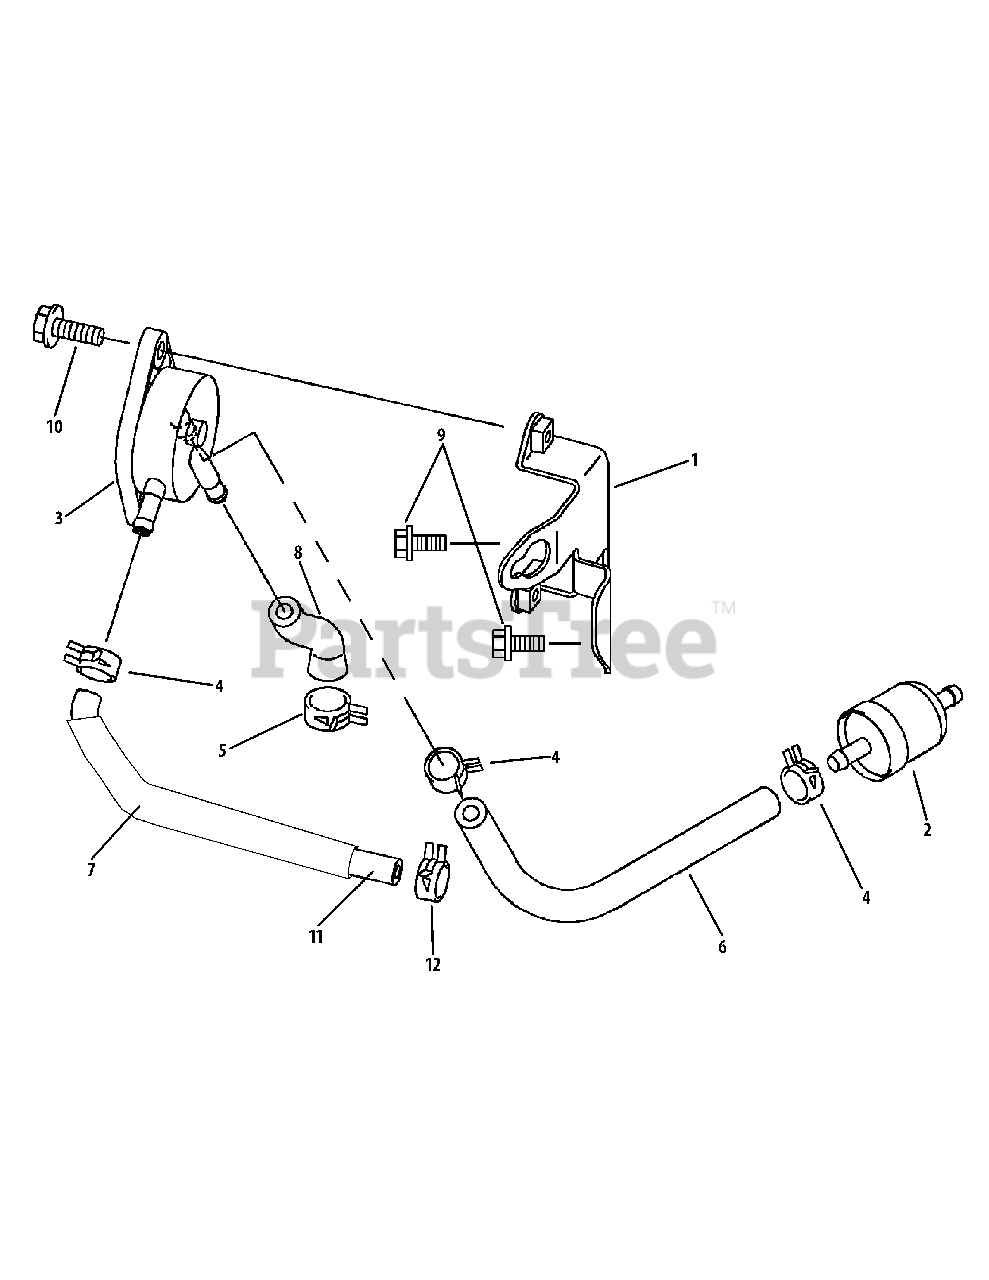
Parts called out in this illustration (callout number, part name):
1	Bracket
2	Fuel Filter
3	Fuel Pump
4	Clamp
6	Tube, 6.35 x 12.7 x 160
9	Flange Bolt, 6 x 16
10	Flange Bolt, 6 x 20
12	Clamp
